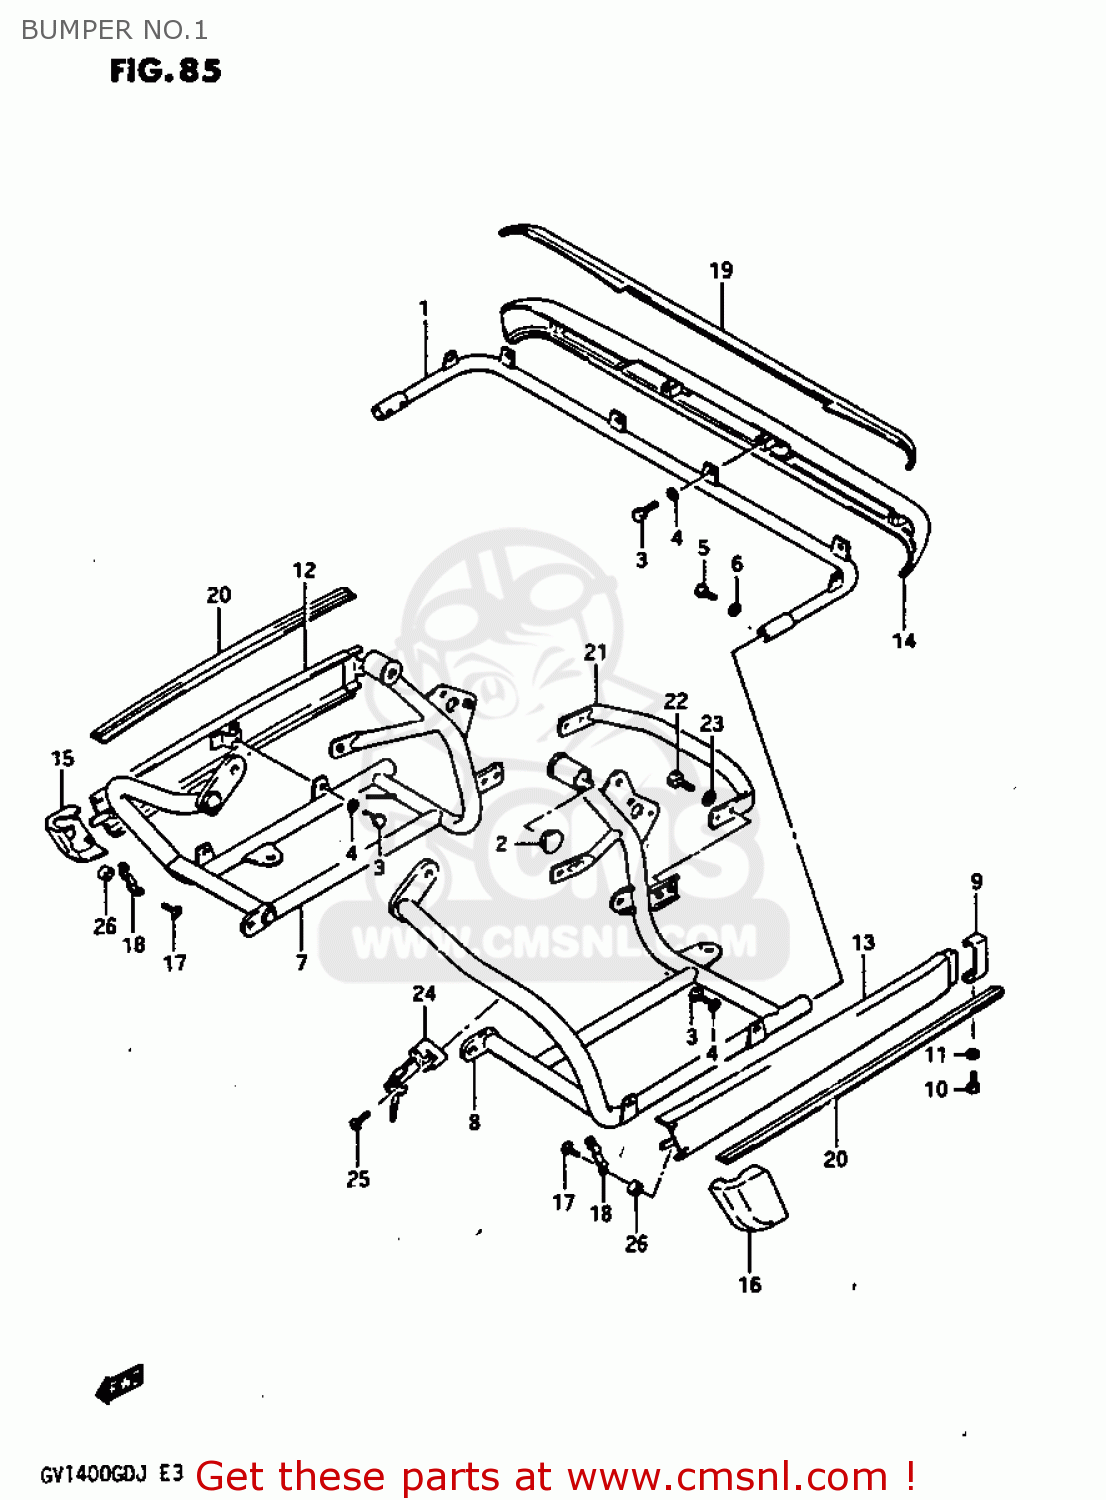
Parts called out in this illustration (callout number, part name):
1	BUMPER,REAR,CENTER
2	CAP,FRAME HANDLE GRIP
3	BOLT
4	WASHER,LOCK
5	BOLT
6	WASHER,LOCK
7	CARRIER, SIDE BAG RH
8	BUMPER,REAR SIDE,LEFT
9	PLATE,SIDE BAG CARRIER,CTR
10	BOLT
11	WASHER,LOCK,10
12	TRIM,SIDE BAG CARRIER
13	TRIM,SIDE BAG CARRIER
14	TRIM,SIDE BAG CARRIER
15	COVER,SIDE BAG CARRIER TRIM R
16	COVER,SIDE BAG CARRIER TRIM L
17	SCREW
18	BRACKET,SIDE BAG CARRIER
19	CUSHION,SIDE BAG RL
20	CUSHION,SIDE BAG TRIM,R/L
21	PIPE COMP,REINFORCING SIDE B
22	BOLT
23	LOCK WASHER
24	LOCK SET,TOOL HOLDER
25	SCREW
26	SPACER (6.6X9X6.5)
